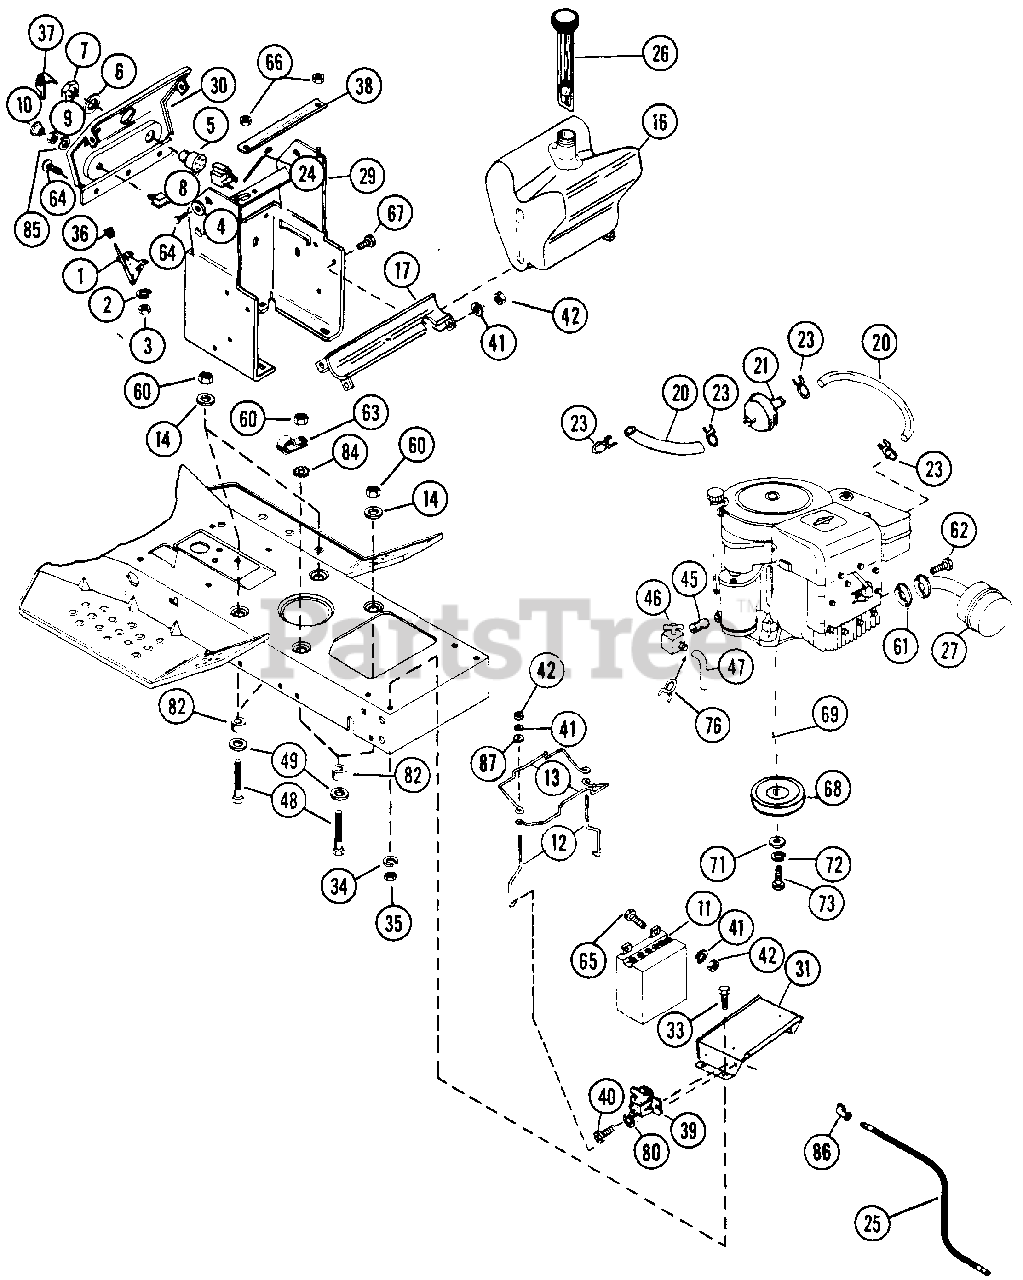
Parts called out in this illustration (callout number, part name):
1	THROTTLE CONTROL
2	WASHER, LOCK NO. 10 SP.
3	NUT
4	WASHER, FLAT .250X.500X.049
5	IGNITION SWITCH
6	WASHER, LOCK INT. TOOTH
7	NUT, JAM 9/16-24
8	LIGHT SWITCH
9	NUT, HEX 1/2-20
10	KNOB
11	BATTERY, 12 VOLT SMALL
12	TIE DOWN
13	HOLD DOWN
14	WASHER, FLAT .312X.734X.065
16	FUEL TANK
17	LOWER TANK SUPPORT
20	HOSE
21	FUEL FILTER
23	HOSE CLAMP
24	TIE DOWN
25	CABLE, BATTERY TO ENGINE BASE
26	FUEL GAUGE
27	EXHAUST MUFFLER
29	DASH BASE
30	DASH
31	BATTERY STAND
33	BOLT, HEX 5/16-18X.625
34	WASHER, LOCK 3/8 SP HEAVY
35	NUT, HEX 5/16-18
36	KNOB
37	KEY, IGNITION SWITCH
38	CLAMP, STRAP
39	SOLENOID
40	SCREW, TAPTITE 1/4-20X.375
41	WASHER, LOCK 1/4 REG.
42	NUT, HEX 1/4-20
45	BUSHING
46	DRAIN LOCK
47	TUBE
48	BOLT, HEX 5/16-18X2.00
49	WASHER, 5/16X1-5/8X.135
60	NUT, LOCK 5/16-18
61	GASKET
62	BOLT, HEX 5/16-18X.75
63	J-CLAMP
64	TAPPING SCREW, 10-16X3/8
65	BOLT, HEX 1/4-20X.875
66	NUT, LOCK 1/4-20
67	BOLT, HEX 1/4-20X.50
68	SHEAVE, ENGINE
69	KEY, STRAIGHT 1/4X2X1/4
71	WASHER, FLAT .500X1.250X.083
72	WASHER, LOCK SP HEAVY
73	BOLT, HEX 7/16-20X1
76	HOSE CLAMP
79	CLIP
80	WASHER, LOCK 1/4 EXT.
82	ENGINE SPACER
84	WASHER, LOCK 5/16 EXT TH TYA
85	WASHER
86	BOOT, BATTERY CABLE
87	WASHER, FLAT .281X.625X.065
